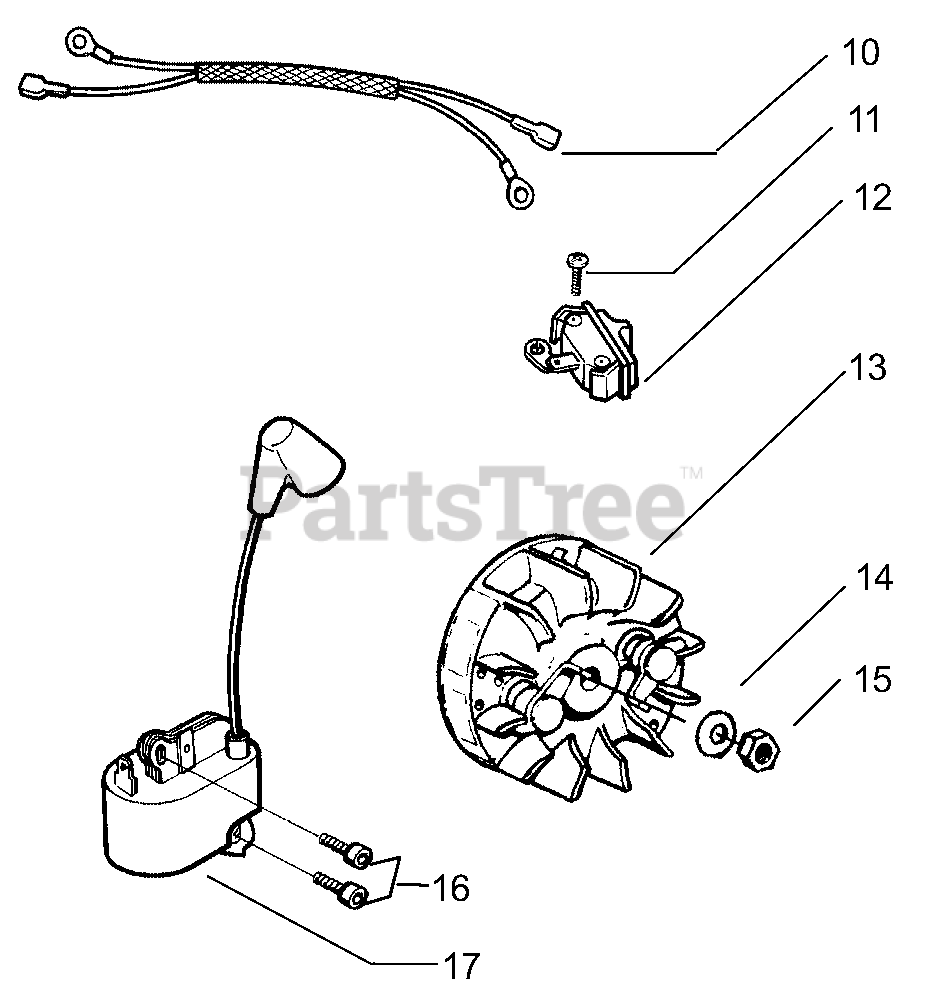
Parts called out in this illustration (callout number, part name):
10	Assy-Leadwire Harness
12	Switch-Ignition
13	Assy. -Flywheel
14	Washer-Flywheel
17	Module - Ignition
